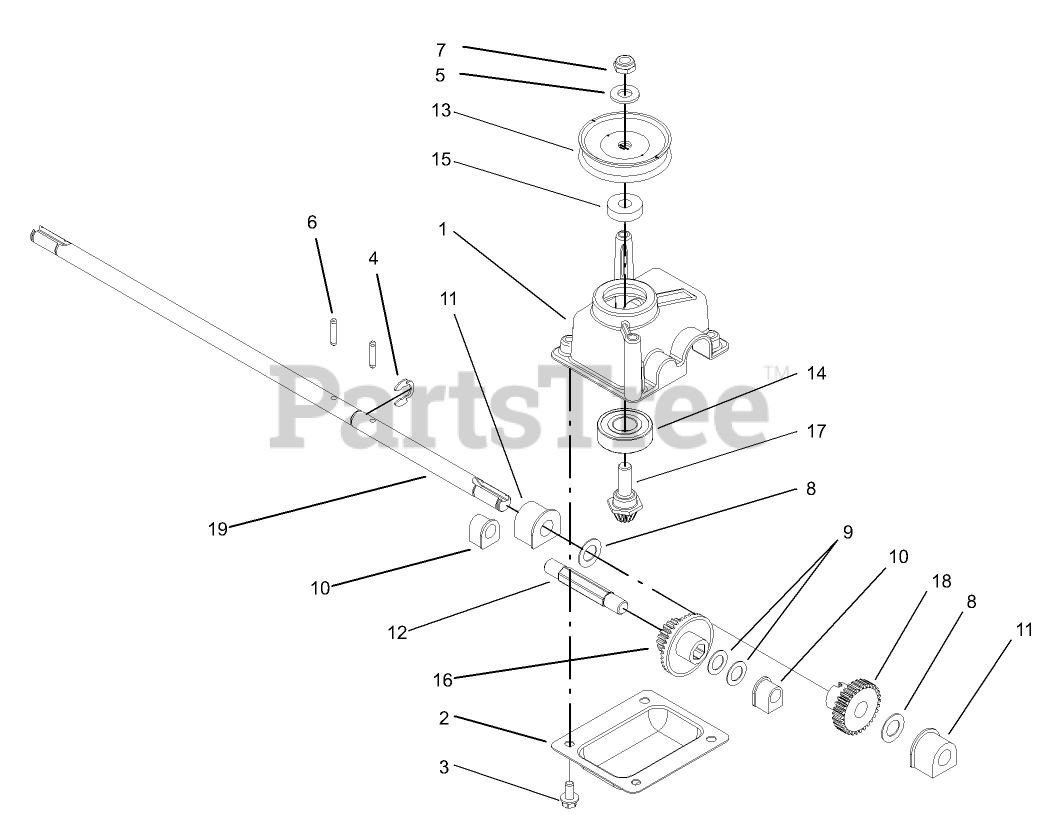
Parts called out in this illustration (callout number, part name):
1	CASE-GEAR
2	COVER-CASE, GEAR
3	SCREW-HWH
4	RING-RETAINING
5	WASHER-FLAT
6	PIN-GROOVE
7	NUT-HEX
8	WASHER-PLAIN
9	WASHER-THRUST
10	BUSHING
11	BUSHING
12	SHAFT-INTERMEDIATE
13	PULLEY-HALF
15	SPACER
16	GEAR-19T SPUR, 37T BEVEL
17	GEAR-PINION, BEVEL
18	GEAR-30T
19	SHAFT-OUTPUT
